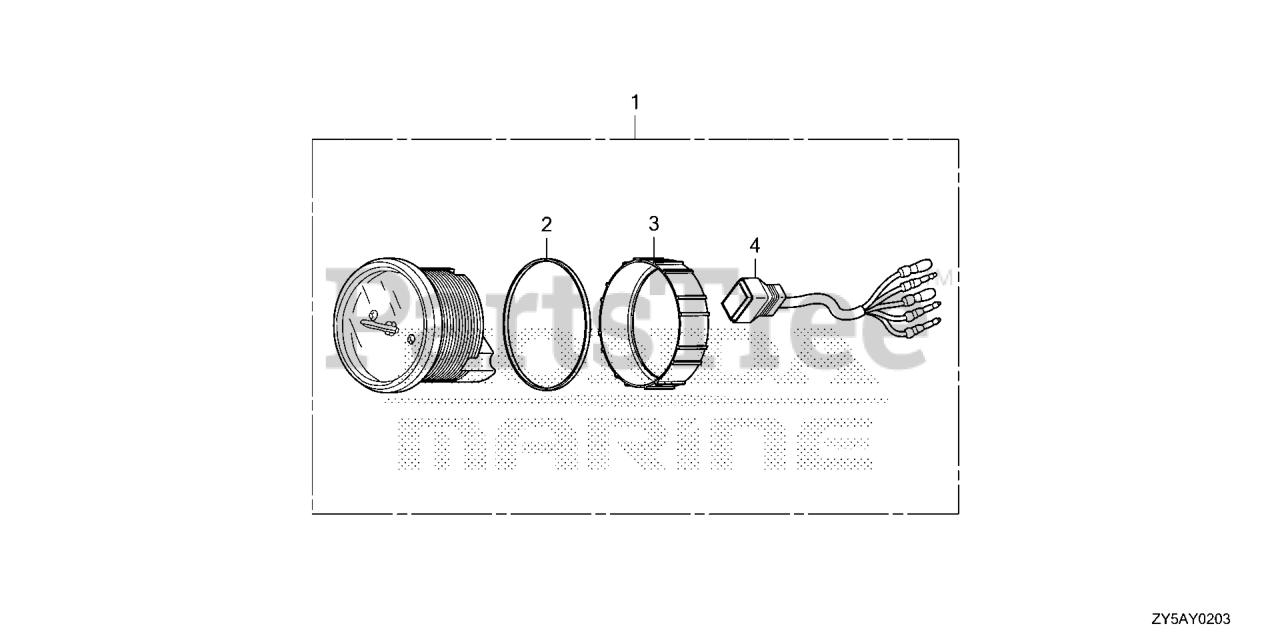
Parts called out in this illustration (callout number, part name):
1	TACHO METER KIT
2	CUSHION RUBBER
3	RING
4	WIRE ASSY.
